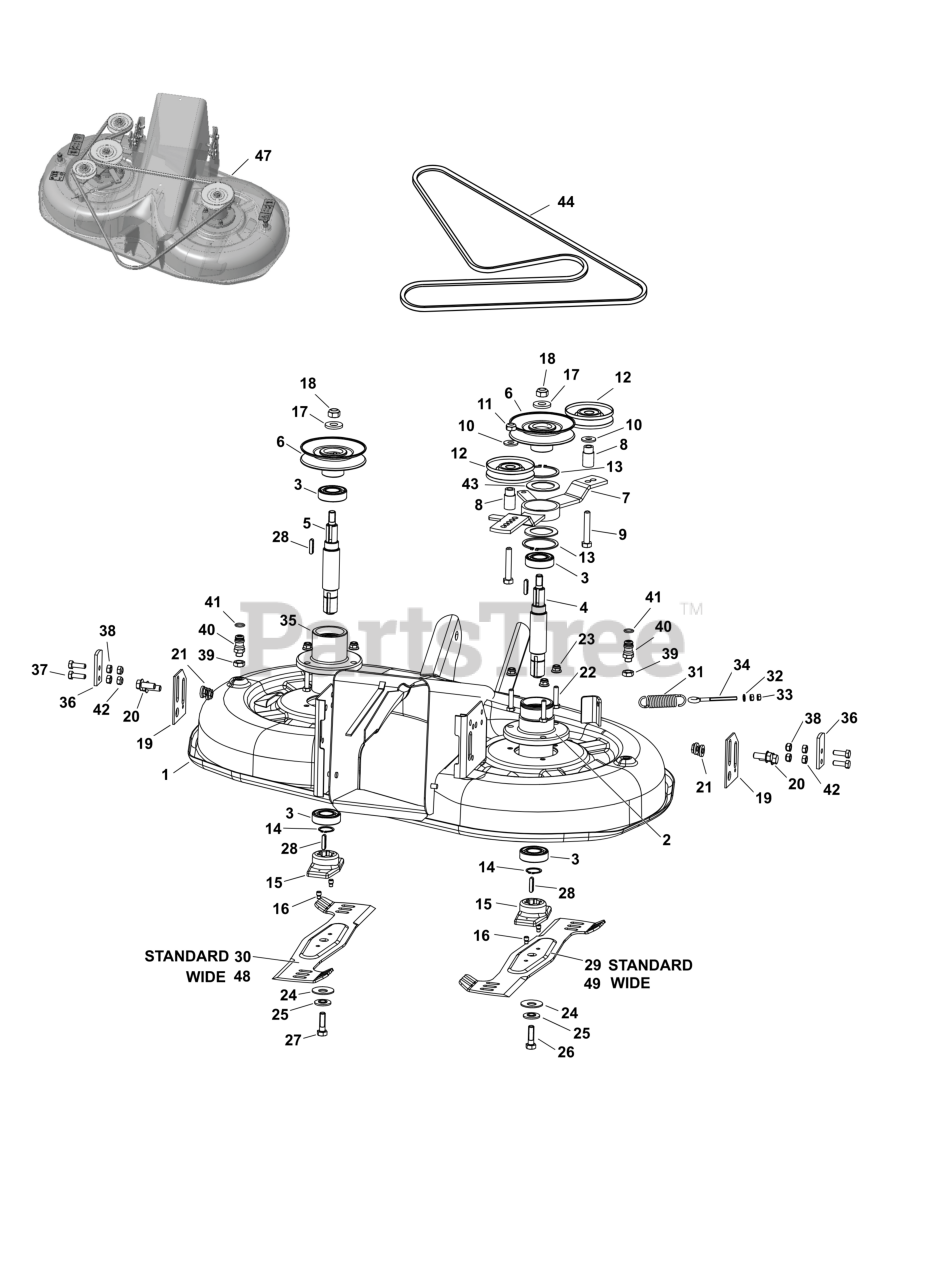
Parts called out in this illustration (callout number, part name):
7	TENSIONER
16	STUD ( 100 PCS )
29	BLADE, Right, 92cm
30	BLADE, Left, 92cm
36	FOOT, Mounting
40	CONNECTOR
47	MOWER DECK
48	BLADE, High Lift, Left, 92cm
49	BLADE, High Lift, Right, 92cm
